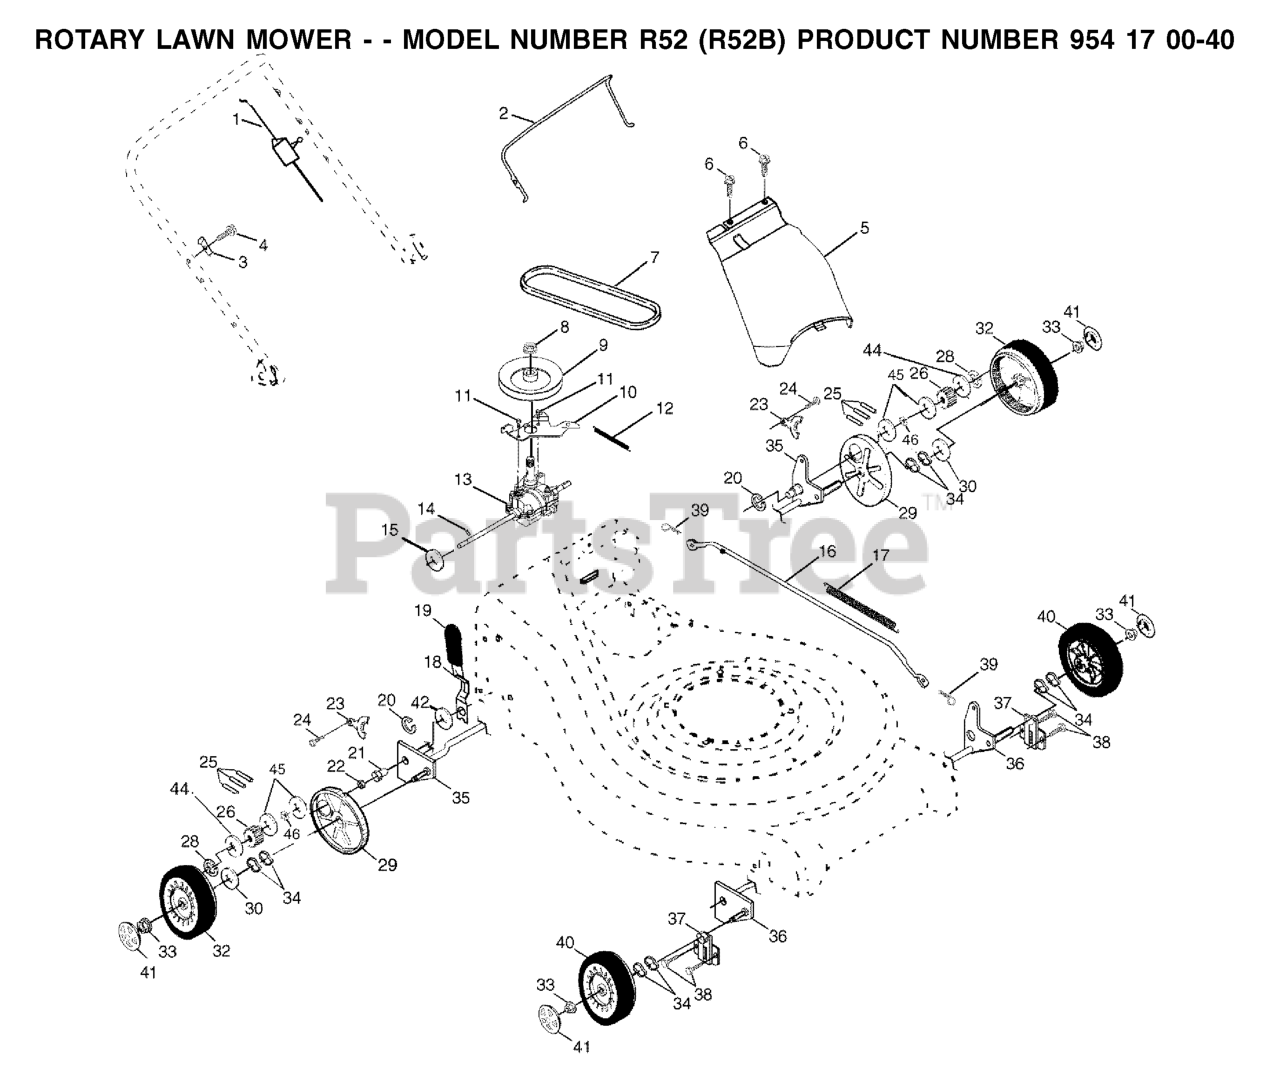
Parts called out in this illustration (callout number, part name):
1	CABLE.DRIVE.21.RWGD.
2	BAIL.CONT.DR.21.RWGD.BLACK
3	DOWNSTOP BRACKET
4	SCREW.HEX.HEAD.WASHER.10-16
5	DRIVE COVER
8	FLANGED LOCKNUT 3/8-16 ZINC
10	BELT GUIDE
11	Screw, Hex Washer Head #10-24 x .668
13	TRANSMISSION ASM. (WALK)
14	PIN.SPRING.THRUST
15	THRUST WASHER
16	ROD CONNECTING
17	SPRING
18	SPRING
19	KNOB
21	RP BEARING SUPPORT
22	BEARING, BALL
23	BRACKET
25	PAWL.DRIVE.ETCHED
26	PINION.DRIVE.WALK
28	E-RING 7/16 RE
29	DUST COVER, WHEEL
30	WASHER FLUT
32	WHEEL.9X2.PR.LP.RADIAL.BK.BB.3
33	HEX FLANGE LOCKNT
34	WAVE WASHER
35	SHAFT ASSY
36	SHAFT ASSY
37	RETAINER.FRONT.SHAFT
39	RETAINER CLIP
40	WHEEL ASMBLY FRONT
41	CAP.HUB.ARC.SPOKE.8".LP
42	WASHER.ZINC.PLATED
45	WASHER.BELLEVILLE (3 2 LB)
